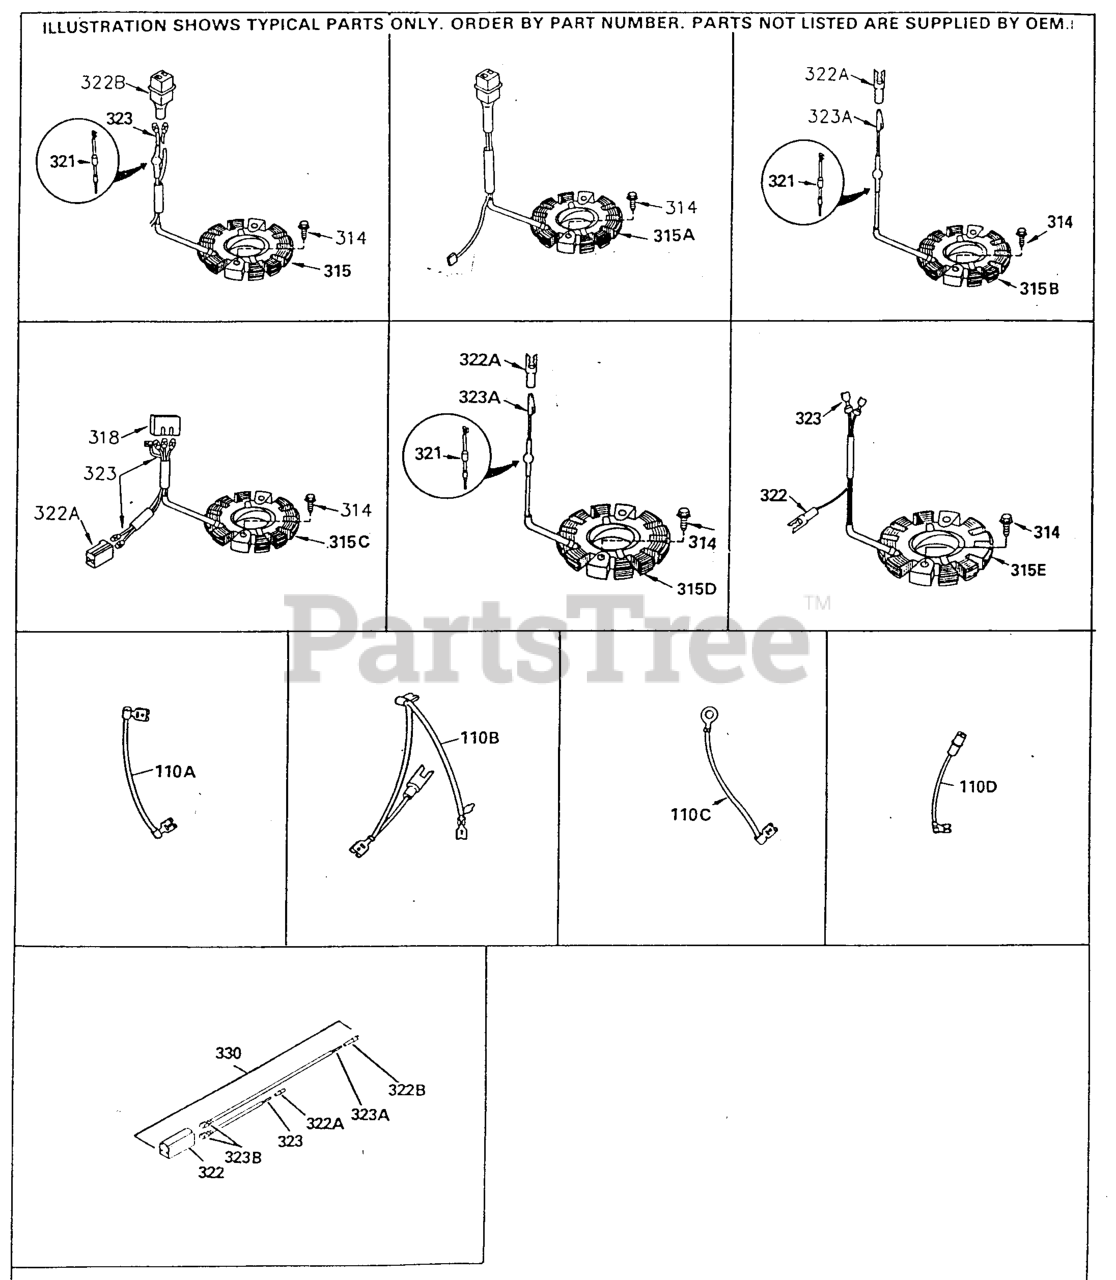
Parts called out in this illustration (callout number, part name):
315	ALT COIL
322	CONNECTOR
323	TERMINAL
